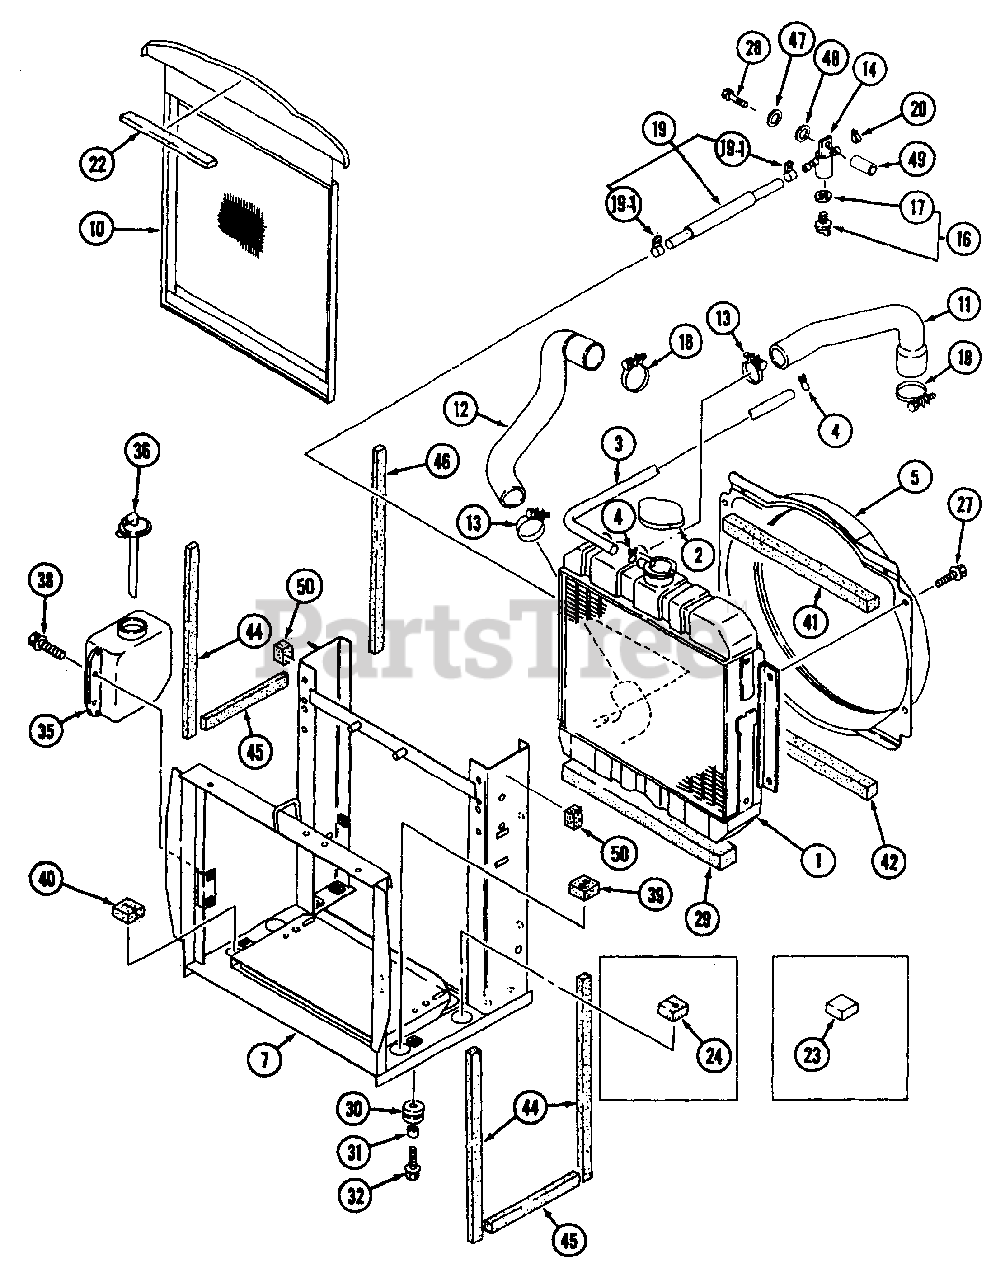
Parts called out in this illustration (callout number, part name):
1	Body, Radiator
7	Bracket, Radiator
16	Water Cock Ass'y.
19	Hose, Drain Ass'y
23	Cushion (Gear)
24	Cushion (HST)
